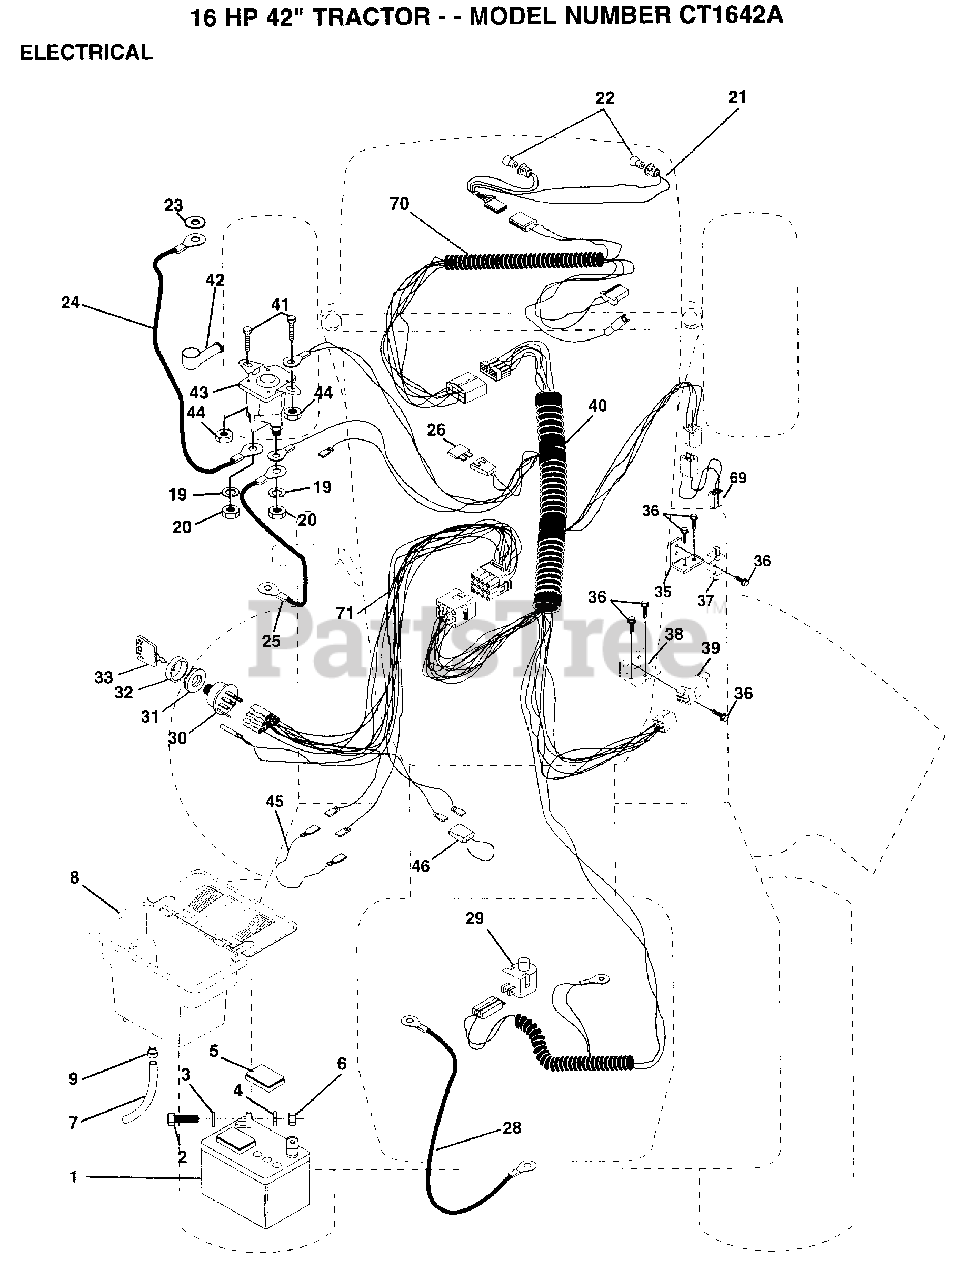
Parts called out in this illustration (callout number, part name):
2	BOLT LT
3	WASHER
4	LOCKWASHER
5	"CAP,BATTERY "
7	TUBE T
9	HOSE CLAMP T
20	NUT
21	"HARNESS,LIGHT SOC"
22	HEADLAMP BULB
23	LOCKWASHER
25	CABLE-BATTERY T
26	FUSE HYT
28	CABLE T
29	SWITCH SEAT
30	SWITCH IGN 4POS
31	NUT IGNITION
32	COVER KEY SWITCH
33	KEY
35	BRACKET LT
36	SCREW
37	SWITCH-INTER. GT
38	BRACKET SWITCH IN
39	SWITCH INTERLOCKT
40	HARNESS IGN B&S
41	BOLT HXHD FIN
44	NUT HXKEP 1/4X20
45	ADAPTER AMMETER
46	PROTECTION LOOP
69	ADAPTER.HARN.SERV
70	HARNESS.ENG.LT.
71	HARNESS DASH LT
